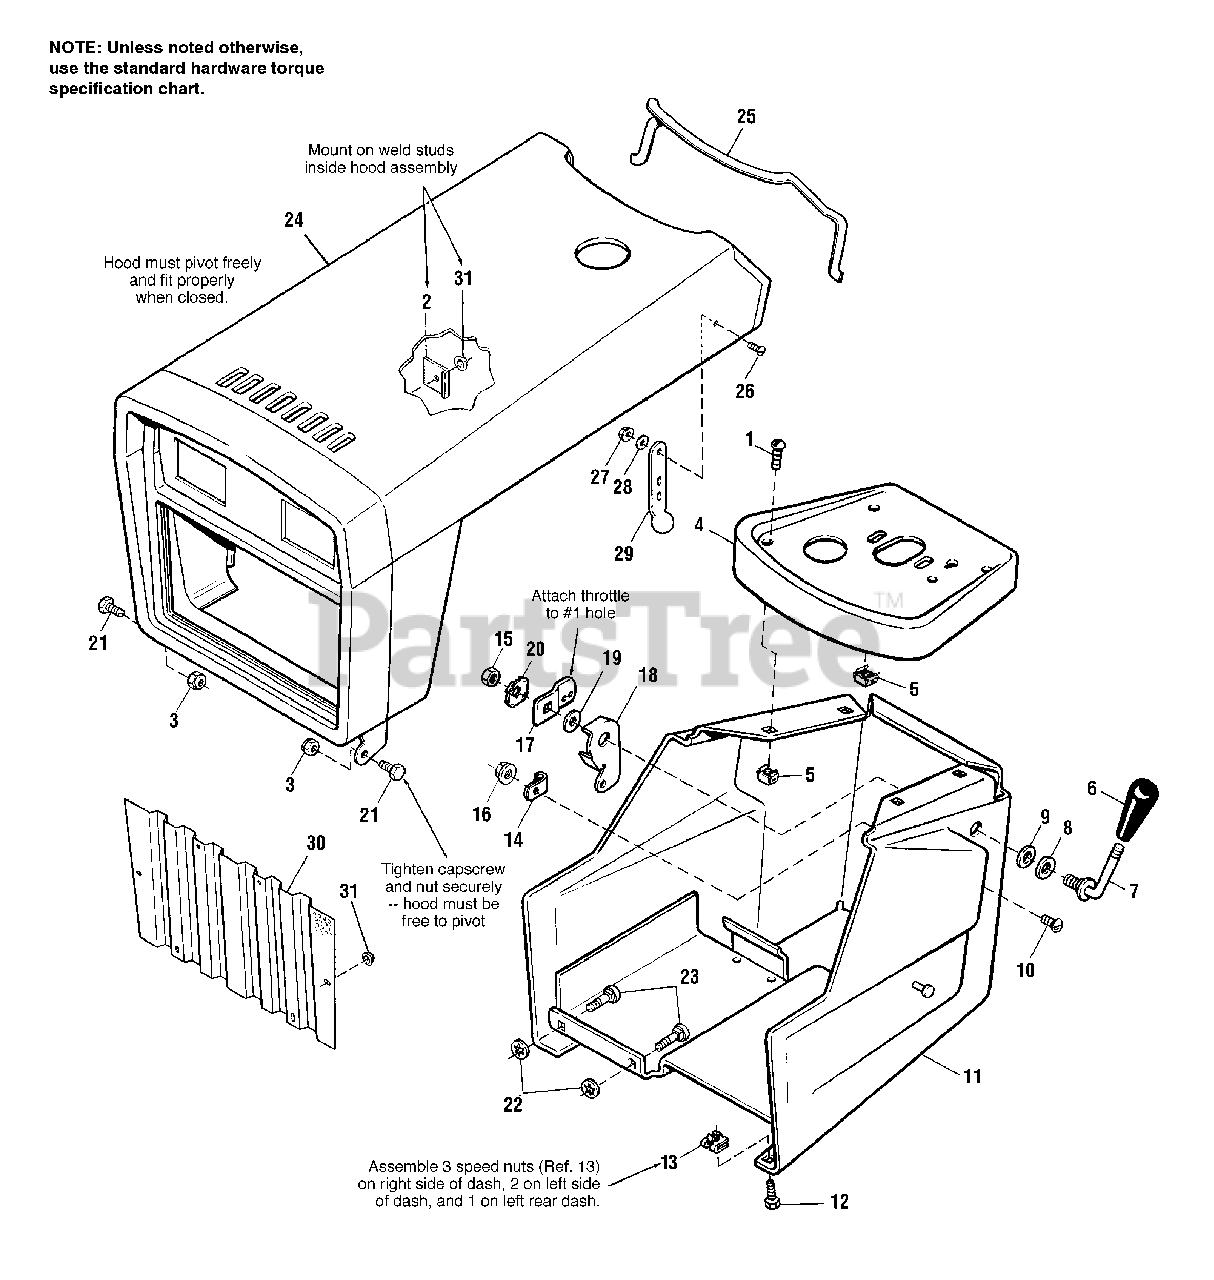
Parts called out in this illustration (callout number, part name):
1	CAPSCREW, Machine, Round Hd, 1/4-20 x 1/2
2	CLIP, Headlight Mounting
3	LOCKNUT, Hex, 3/8-16
4	PANEL, Instrument
5	SPEED NUT, Tinnerman
7	HANDLE, Throttle Control
10	CAPSCREW, Truss Hd, #10-32 x 1/2
11	DASH ASSEMBLY
12	CAPSCREW, Hex, Self-Tapping, #14AB x 3/4
13	NUT, Speed
14	CLIP, Control Cable
15	LOCKNUT, Hex, 3/8-16
16	NUT, Hex, Washer, #10-32
17	ARM, Throttle
18	STOP, Throttle
20	LOCKWASHER, Dished Type, 3/8
21	CAPSCREW, Hex Hd, 3/8-16 x 1
22	PUSH NUT
23	CARRIAGE BOLT, 5/16-18 x 3/4
24	HOOD & GRILLE ASSEMBLY
25	MOULDING, Hood
26	CAPSCREW, Truss Hd, #10-32 x 1/2
27	LOCKNUT, Hex, #10-32
28	WASHER
29	STRAP, Hood
31	LOCKNUT, Pal
